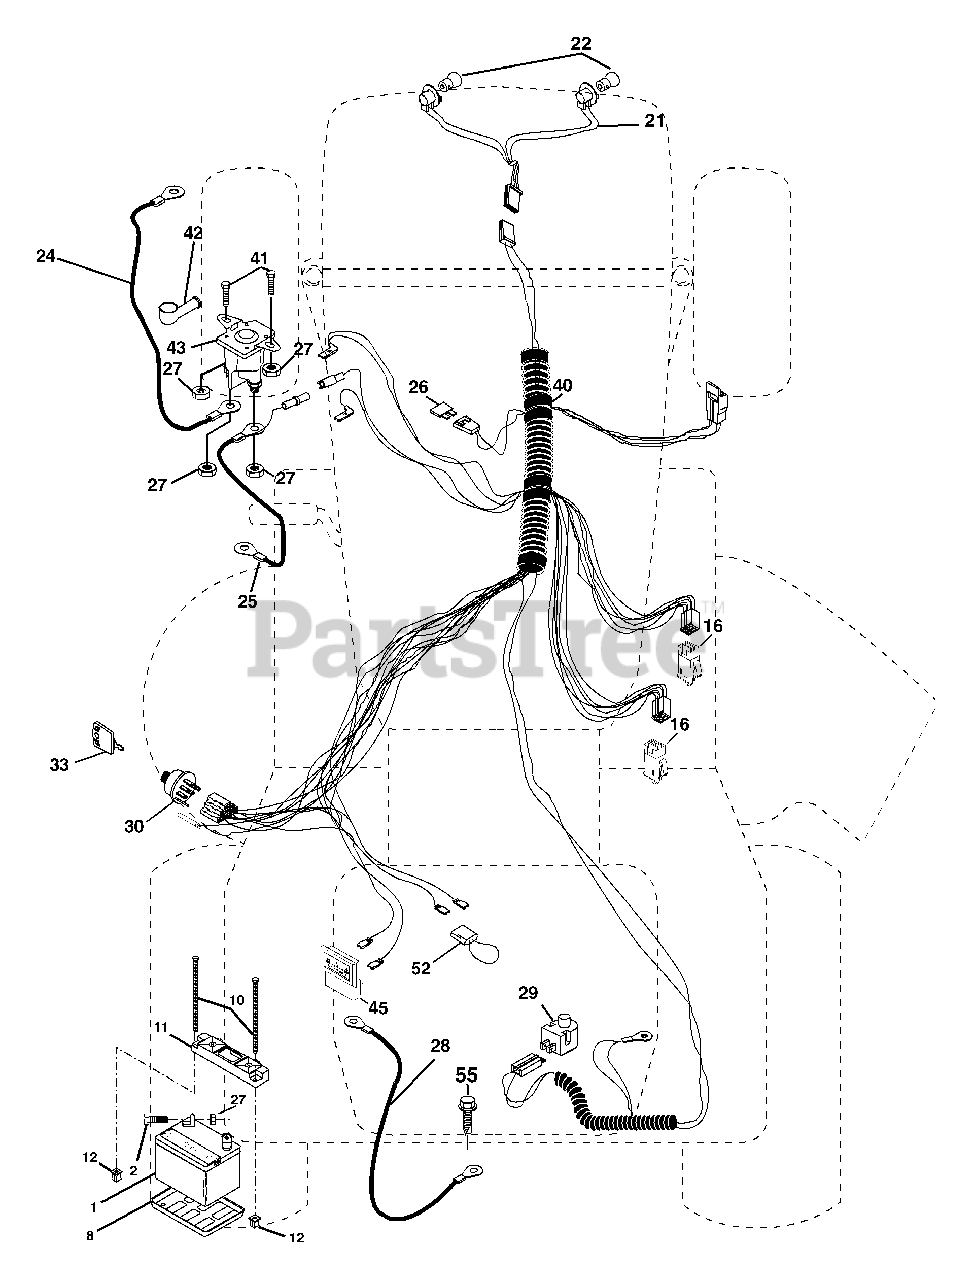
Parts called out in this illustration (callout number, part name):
1	Battery
2	Bolt Hex Hd 1/4-20 unc x 3/4
8	Tray Battery
10	Bolt Btr frt 1/4-20 x 7.5 zinc
11	Holddown battery
12	Nut Push Nylon 1/4
16	Switch Interlock
21	Harness Socket Light
22	Bulb, Light # 1156
24	Cable Battery
25	Cable Battery 6 Ga. Red w/16 wire
26	Fuse
27	Nut Keps Hex 1/4-20 unc
28	Cable Ground 21" Blk 6 Ga.
29	Switch Plunger Nc Gray
30	Switch Ign
33	Key Ign Molded Generic
40	Harness Ign
41	Bolt Fin Hex 1/4-20 unc x 1/2
42	Cover Terminal Red
43	Solenoid
45	Ammeter Rectangular
52	Protection Loop
55	Screw Thdrol 5/16-18 x 1/2
